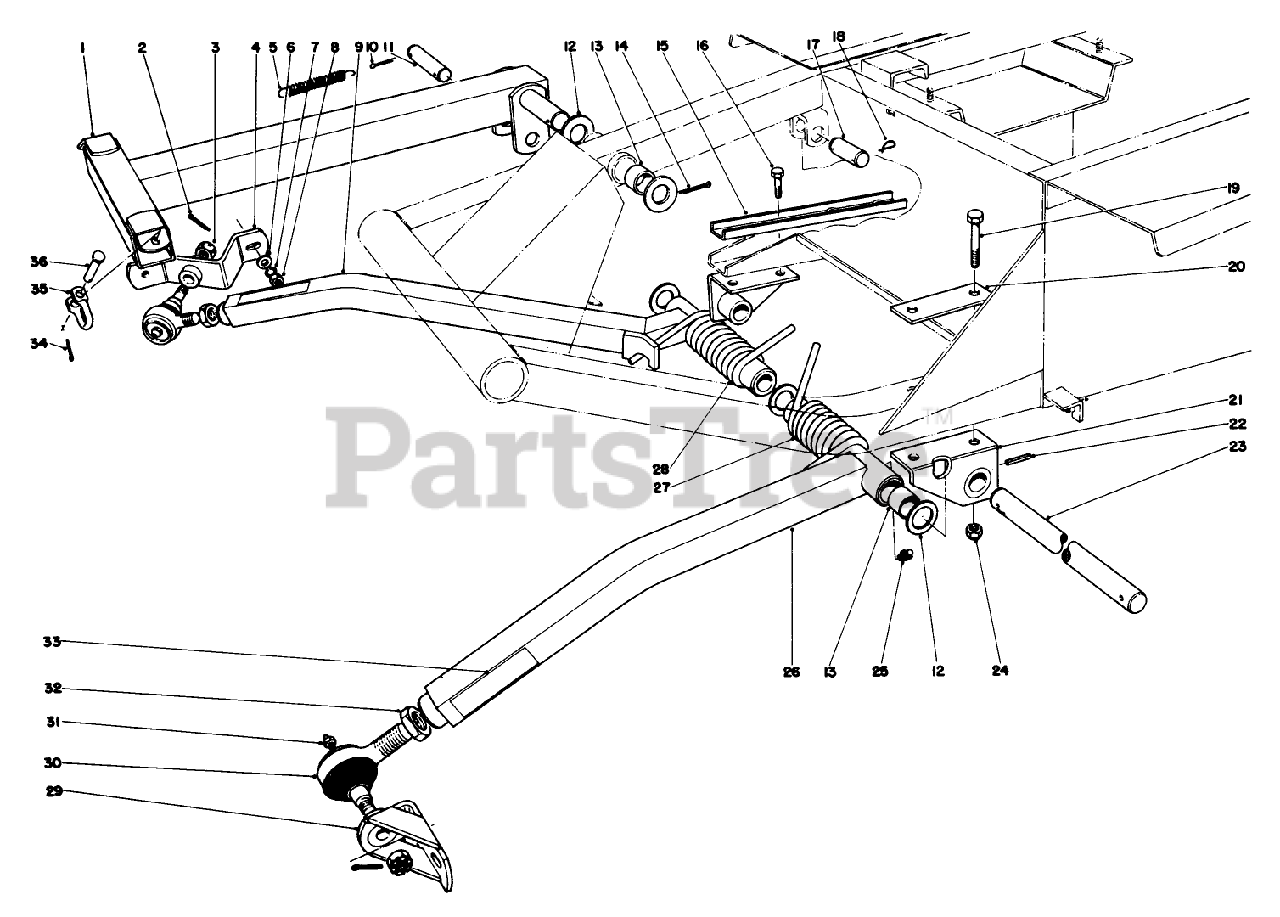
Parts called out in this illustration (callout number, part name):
1	Lift Arm
2	PIN-COTTER
3	NUT-SHH
4	Ball Joint Mount
5	SPRING-EXTENSION
6	WASHER-FLAT
7	WASHER-LOCK
8	NUT-HEX
9	Push Arm R.H. (Incl. Ref. #13 & 25)
10	PIN-COTTER
12	WASHER-FLAT
13	BUSHING
14	PIN-COTTER
15	Support Reinforcement
16	SCREW-HH
17	PIN-CLEVIS
18	PIN-LYNCH
19	SCREW-HH
20	SUPPORT PLT
21	Bracket-Push Arm
22	PIN-SPIRAL
23	SHAFT-PIVOT
24	NUT-LOCK, NI
25	FITTING-GREASE
26	Push Arm L.H. (Incl. Ref. #13 & 25)
27	Spring-Torsion LH
28	Spring-Torsion RH
29	LH BALL JOINT MT WA
30	Ball Joint
31	FITTING-GREASE
32	NUT-HJ
33	Decal Warning
34	PIN-COTTER
35	SHACKLE
36	PIN-CLEVIS
